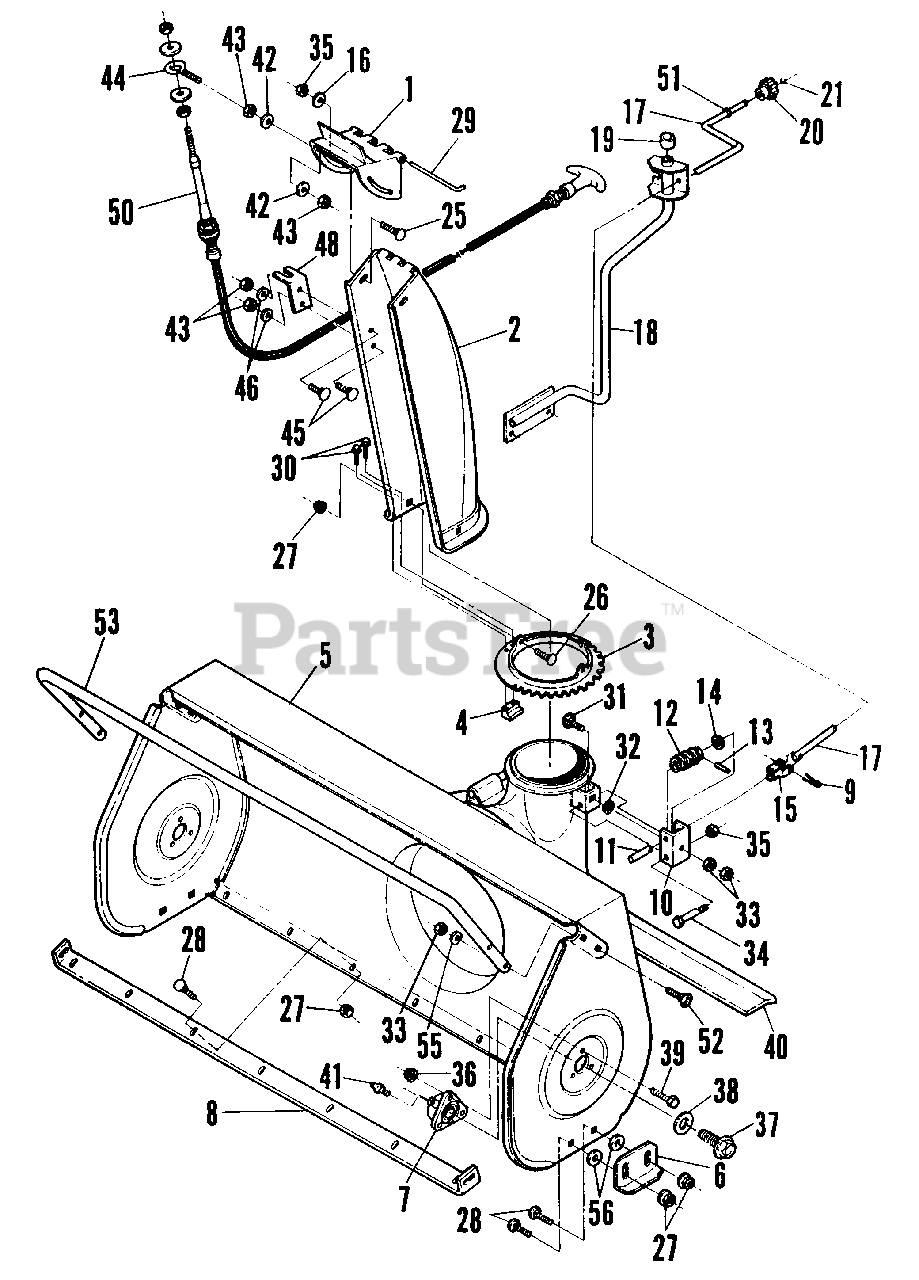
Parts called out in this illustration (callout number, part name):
1	DEFLECTOR, Discharge
2	CHUTE & DECAL ASS'Y.
3	RING, Chute
4	RETAINER, Chute Ring
5	HOUSING & DECAL ASS'Y.
6	SHOE, Skid
7	BEARING, Auger Shaft
8	BLADE, Scraper
9	PIN, 1/8 x 1 1/4" Cotter
10	BRACKET, Worm
11	SHAFT, Worm
12	WORM
13	ROLL-PIN, 1/8 x 3/4"
14	WASHER, Spring Steel
15	CONNECTOR
16	WASHER, 5/16" Flat
17	CRANK, Chute
18	BRACE, Chute Crank
19	CAP, Crank Brace
20	KNOB, Chute Crank
21	NUT, 5/16 - 18 Hex Lock
25	SCREW, 5/16 - 24 x 3/4" Hex Head Cap
26	BOLT, 5/16 - 18 x 5/8" Carriage
27	NUT, 5/16 - 18 Hex Flange Lock
28	BOLT, 5/16 - 18 x 3/4" Carriage
29	PIN, Hinge
30	SCREW, #10 - 24 x 5/8" Self-Tapping
31	BOLT, 5/16 - 18 x 1" Carriage
32	RETAINER, Bolt
33	NUT, 5/16 - 18 Hex
34	SCREW, 5/16 - 24 x 2 1/2" Hex Head Cap
35	NUT, 5/16 - 24 Hex Lock
36	NUT, 1/4 - 20 Hex Flange Lock
37	SCREW, 3/8 - 16 x 3/4" Self Tap
38	WASHER, 3/8" Flat
39	BOLT, 1/4 - 20 x 3/4" Hex Flange Lock
40	BAR, Stiffener
41	FITTING, Lube (Press fit for .187 hole-no ball)
42	WASHER, 1/4" Flat
43	NUT, 1/4 - 20 Hex
44	BOLT, 1/4 - 20 Eye
45	BOLT, 1/4 - 20 x 1/2" Carriage
46	WASHER, 1/4" Internal Tooth Lock
48	MOUNT, Cable
50	CABLE, Control
51	BUSHING
52	BOLT, 5/16 - 18 x 1 1/2" Curved Head
53	DRIFT CUTTER
55	WASHER, 5/16" Split Lock
56	BRACKET, Cable Support
